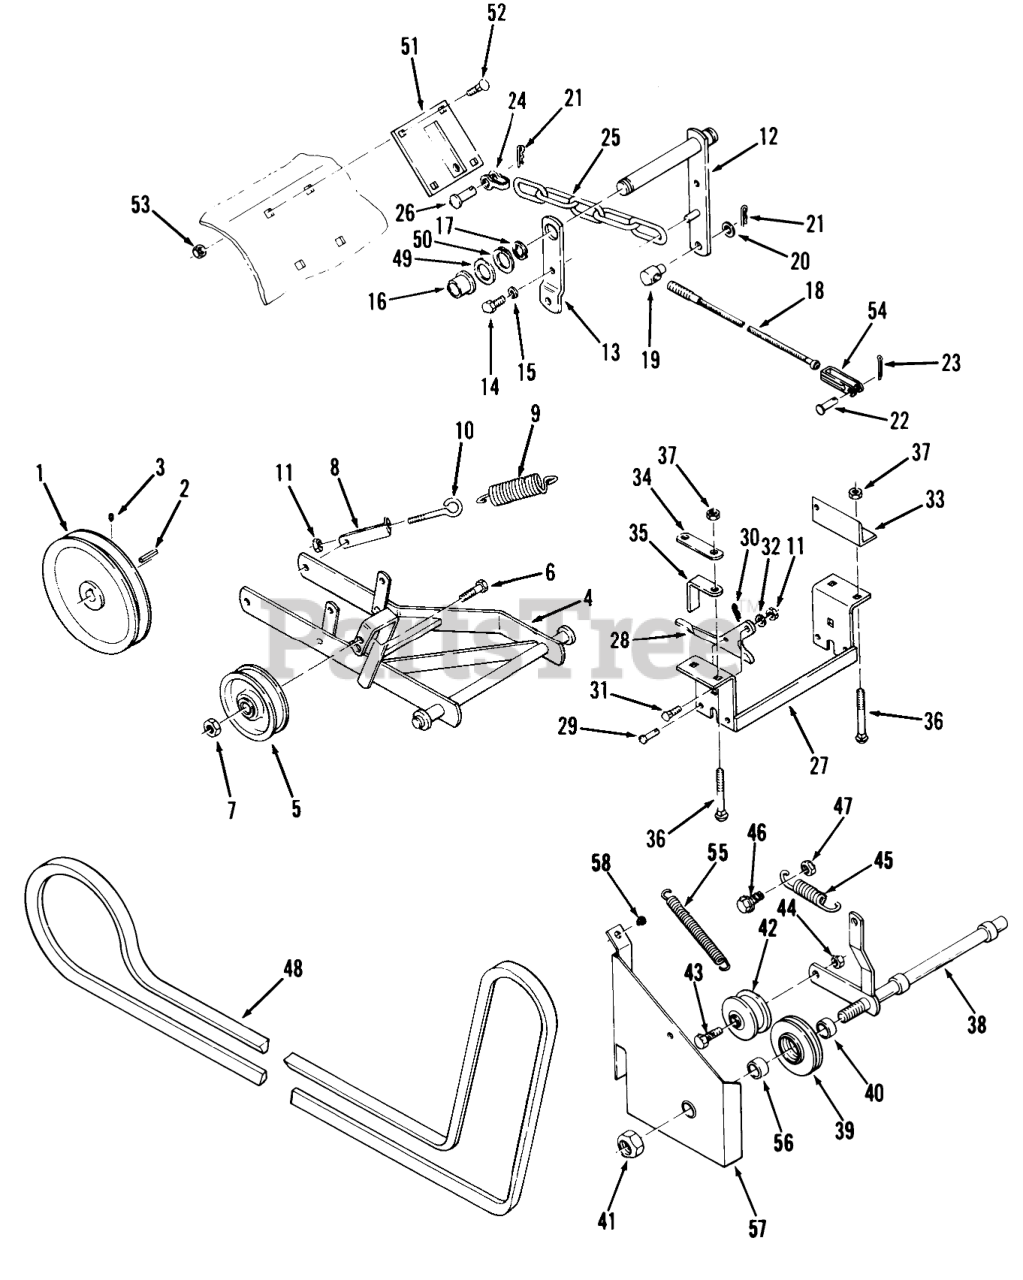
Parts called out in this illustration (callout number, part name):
1	Pulley
2	KEY-STRAIGHT
3	Set Screw
4	Hitch
5	Flat Idler
6	HEX HD CAP SCREW
7	Nut
8	Bracket-Spring
9	SPRING
10	EYEBOLT
11	NUT
12	ASSY-LEVER R
13	LOCK BRACKET R
14	Bolt
15	Lockwasher
16	BUSHING-BRONZE
17	E-RING
18	CABLE
19	TRUNNION-CLUTCH ROD
20	Washer
21	Hairpin
22	Pin
23	Cotter Pin
24	Clevis
25	CHAIN-LIFT
26	Clevis Pin
27	Bracket
28	PLATE-LATCHING
29	Pin
30	Hairpin
31	Bolt
32	Washer
33	LINK-BRACKET R
34	BRACKET-REAR LINK MOUNTING
35	SPACER-BRACKET
36	Bolt-Carriage
37	Nut
38	ASSY-FRONT IDLER R
39	Pulley-V
40	Spacer
41	Nut
42	IDLER PULLEY
43	BOLT
44	Nut
45	SPRING-BRAKE
46	HHCS
46	BOLT
47	Nut
48	V BELT
49	WASHER
50	WASHER-SHIM
51	Lift Plate
52	Bolt
53	Nut
54	CLEVIS-SHORT
54	CLEVIS-LONG
55	SPRING-EXTENSION
56	SPACER
57	Guard Idler
58	GROMMET
